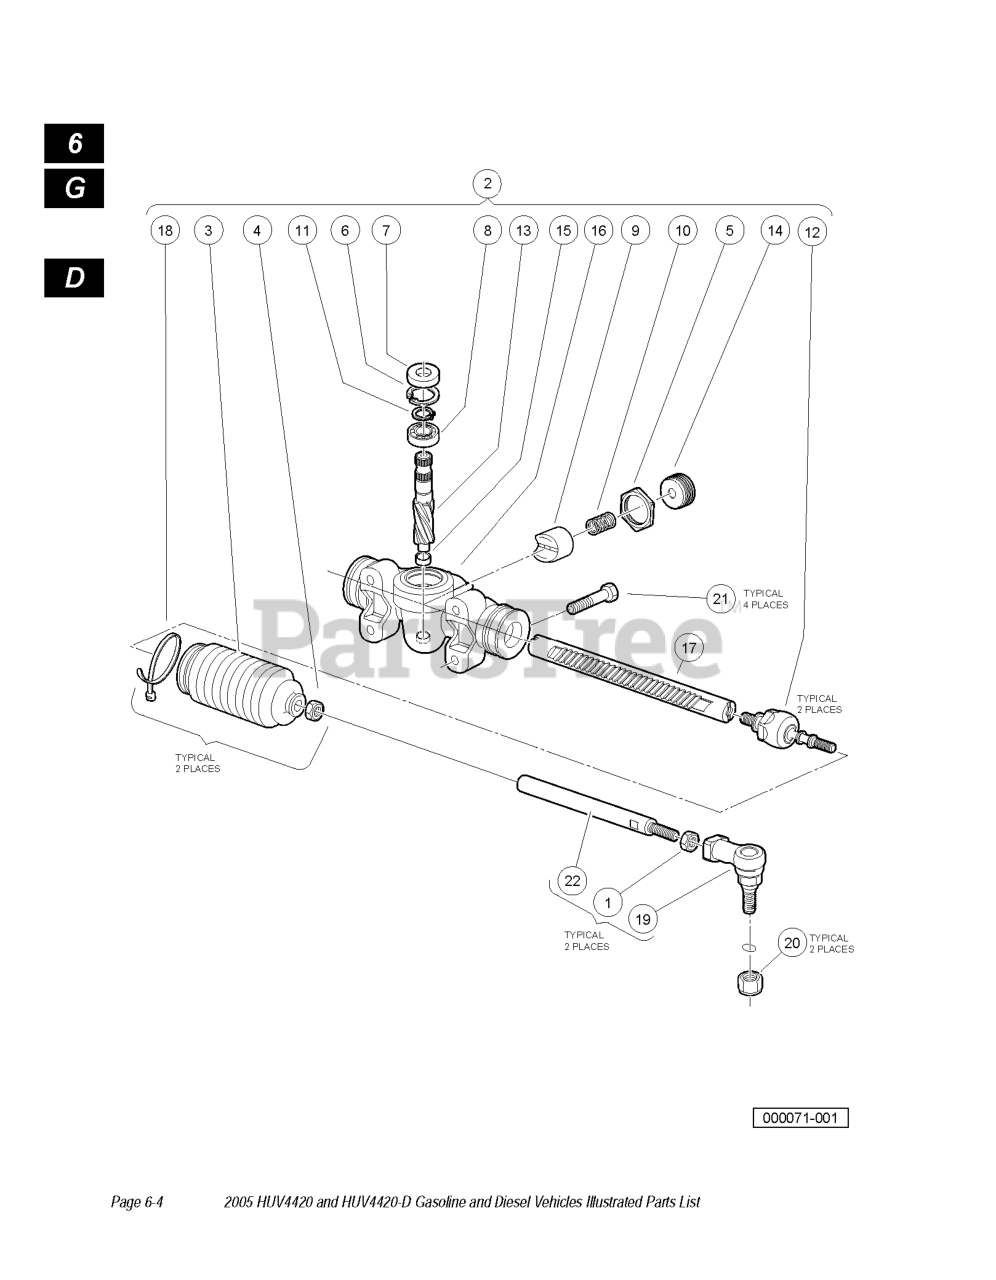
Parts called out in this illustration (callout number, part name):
1	12MM HEX NUT
2	STEERING RACK
3	BELLOWS, LONG
4	12MM HEX NUT
5	RACK SCREW LOCKNUT
7	SEAL, STEERING PINION DUST
8	BEARING BALL
9	SUPPORT YOKE
10	RACK GUIDE PRESSURE SPRING
11	C-TYPE STOP RING
12	INNER BALL JOINT ASM
18	TIE WRAP, 8" NYLON
19	TIE ROD END
20	LOCKNUT, M12-1.25 NYLON
22	LINK, DRAG, WT
